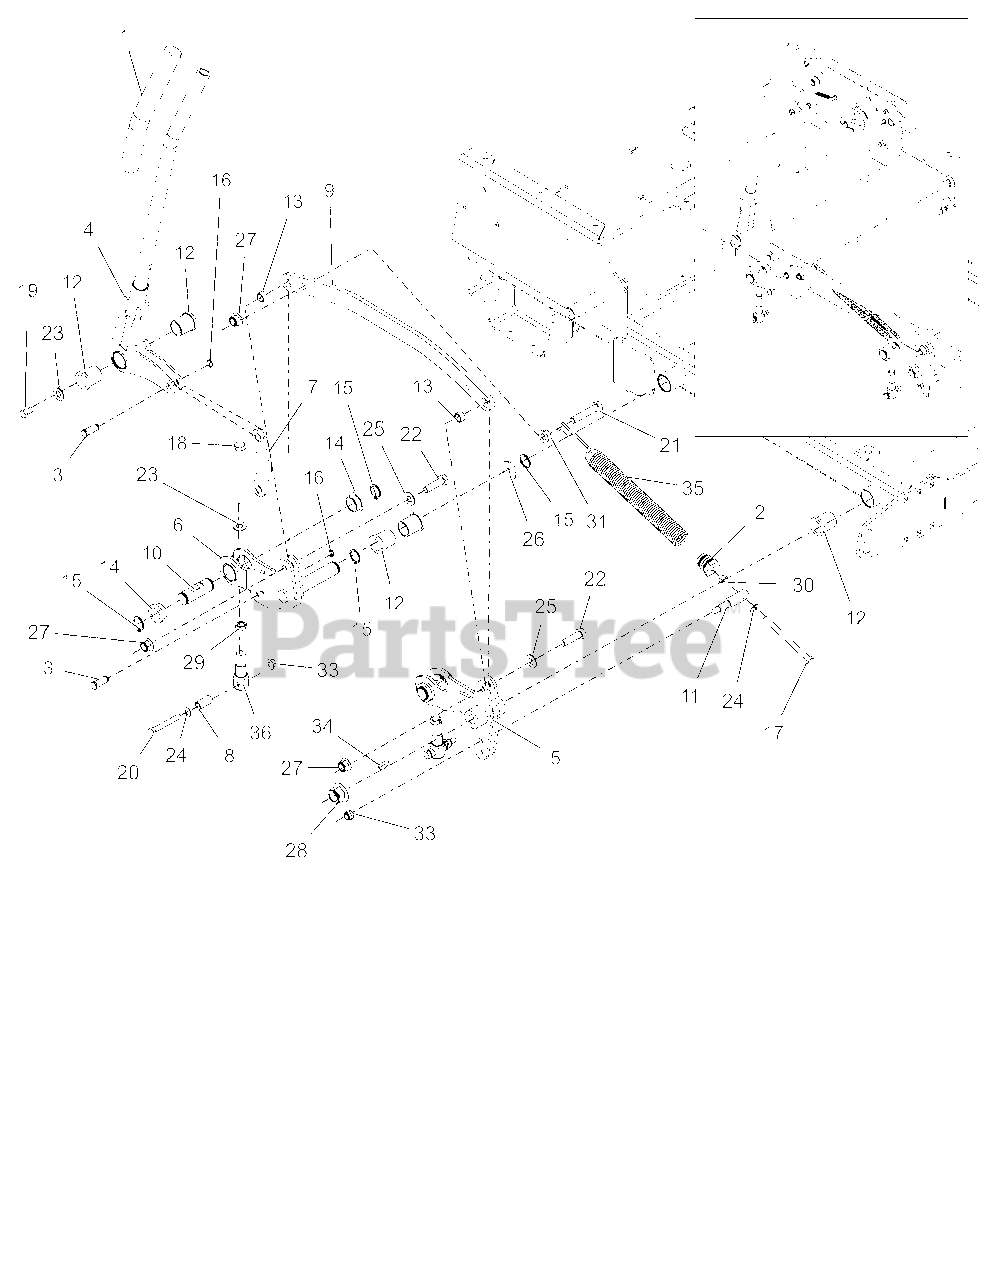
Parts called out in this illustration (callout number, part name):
1	GRIP, HANDLEBAR 1.00X1.38X11.3
2	PLUG, SPRING
3	PIN, CLEVIS .500 SNAP RING
4	HAND LEVER - PROPANE
5	WLDMT, PSTANCE TAPERED HUB
6	WLDMT, PSTANCE DECK ARM
7	WLDMT, DECK LIFT LINK
8	SPACER, DECK LEVELING
9	ARM, DECK LIFT
10	PIN, DECK LIFT
11	TRUNION, DECK LIFT
12	BSHG-FLG 1.00X1.25X1.50X1.50
13	BSHG-SLV .513 X .748 X .420
14	BSHG,FLG 1.0 X 1.25 X 1.5 X .6
15	RG-RTNG-EXT 1.00X.078
16	RG-RTNG-EXT .500X.050 (SNAP)
17	BLT-HEX .38-16X5.00 GR5 FTH YZ
18	BOLT, 1/2-13 X 5.0 2.5 THREAD
19	@BLT-HEX .38-16X.75 GR5 YWZC
20	BLT-HEX .38-16X2.75 GR8 YWZC
21	@BLT-HEX .50-13X2.50 GR5 YWZC
22	@BLT-HEX .50-13X1.75 GR5 YWZC
23	FLATWASHER 1/2 SAE HARD 15906
24	@WSHR-FL-STL.406X.812X.065 YWZ
25	@WSHR-FL-STL.531X1.06X.095YWZC
26	WSHR-FL-STL .380X1.50X.125YWZC
27	@NUT-LK-NYL-FLG .50-13 YWZC
28	@NUT-LK-NYL-FLG .75-10 YWZC
29	NUT-JAM .50-13 YWZC
30	@NUT-HEX .38-16 YWZC
31	NUT-SPNLK-FLG .50-13 YWZC
33	@NUT-LK-NYL-FLG .38-16 YWZC
34	KEY-WDRF .25X1.00 HRD #15
35	SPRING, DECK LIFT
36	LINK, DECK LIFT FORMED
